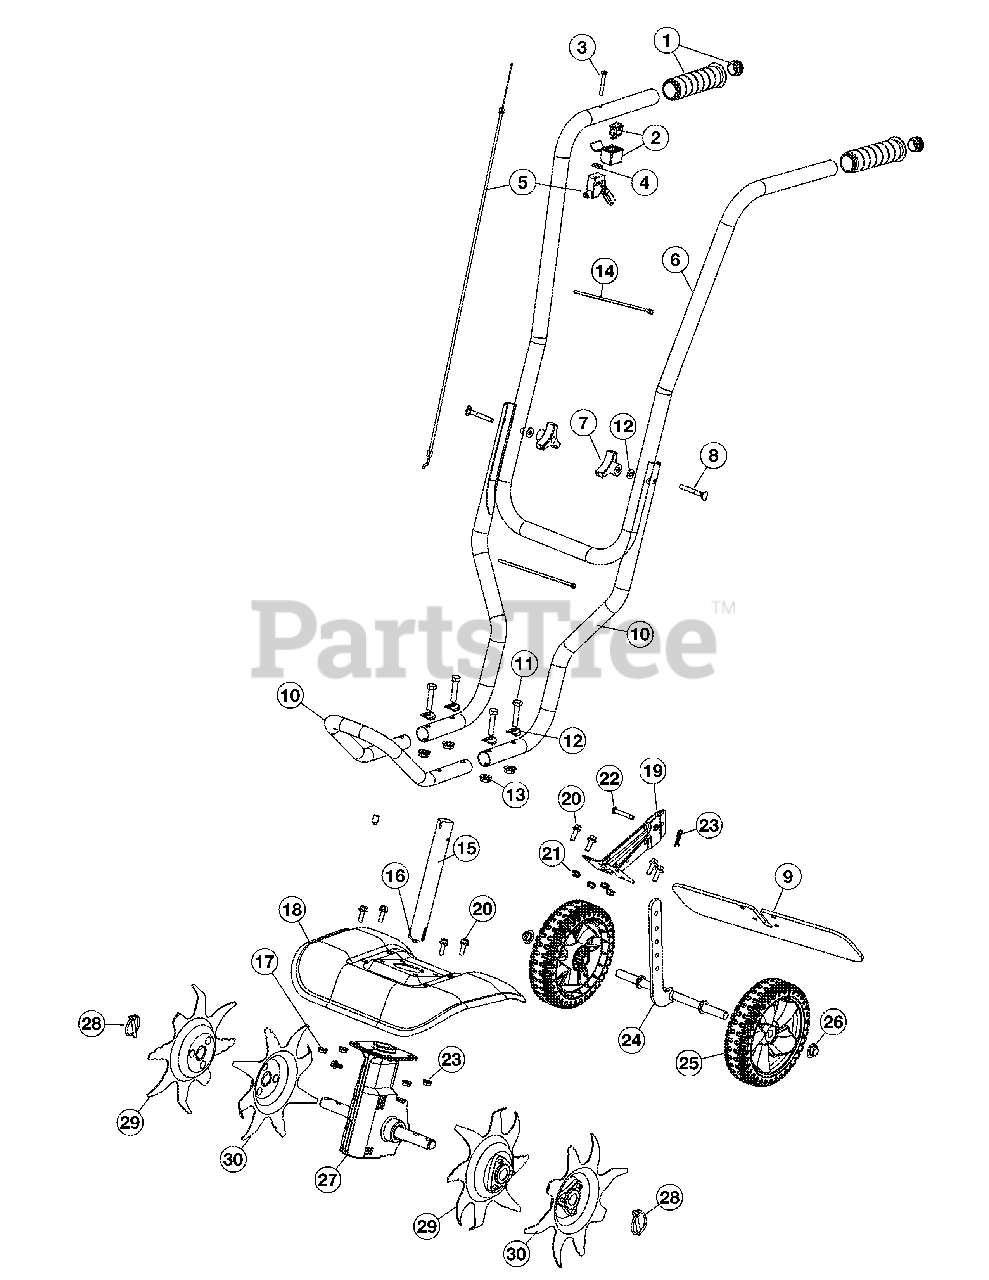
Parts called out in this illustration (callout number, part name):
2	Switch Assembly
3	Screw
5	Throttle Assembly
6	Upper Handle
9	Debris Shield
10	Lower Handle Assembly
11	Bolt
12	Washer
14	Cable Tie
15	Boom Assembly (Incl. Ref No. 16)
16	Flex Shaft
17	Bolt
18	Tine Shield
19	Wheel Bracket Assembly
22	Clevis Pin
23	Cotter Pin
24	Wheel Support Bracket
29	Tine (RH Outer/ LH Inner)
30	Tine (LH Outer/ RH Inner)
